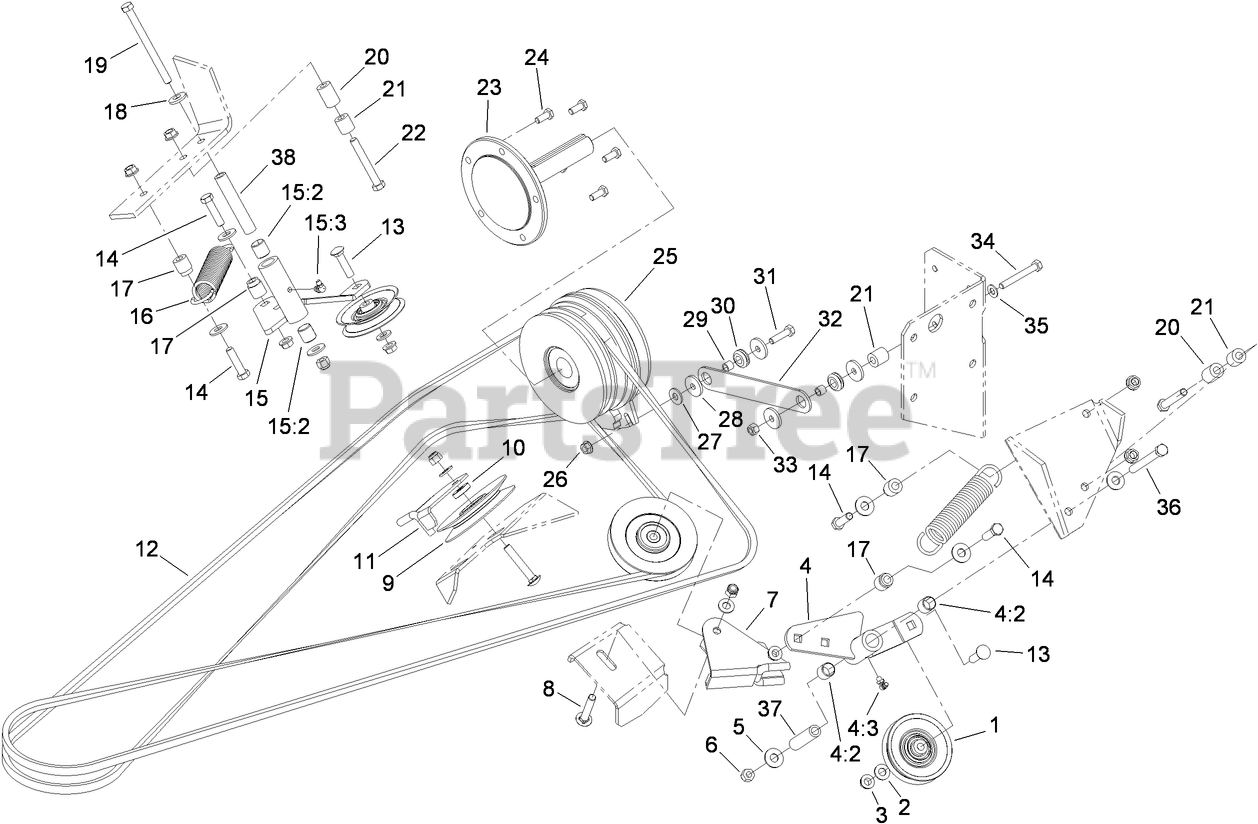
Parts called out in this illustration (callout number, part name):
1	SHEAVE
2	WASHER-FLAT
3	NUT-HHF, WHIZ
4	LH IDLER ASM
4:2	SLEEVE-BEARING
4:3	FITTING-GREASE, 90 DEG
5	WASHER-FLAT
6	NUT-LOCK, NI
7	GUARD-BELT SHEAVE, LH
8	BOLT-CARR, SHORT NECK
9	SHEAVE
10	SPACER-BRACKET, GUIDE
11	GUARD-BELT SHEAVE, RH
12	BELT-V
13	SCREW-HH
14	SCREW-HH
15	RH IDLER ASM
15:2	SLEEVE-BEARING
15:3	FITTING-GREASE, 90 DEG
16	SPRING-EXTENSION
17	SPACER-TIGHTENER, BELT
18	WASHER-BELLEVILLE
19	SCREW-HH
20	SPACER-HYDRO CONTROL, LH
21	SPACER-STRAP, CLUTCH
22	SCREW-HH
23	SHAFT-STUB
24	SCREW-HH
25	CLUTCH KIT
26	NUT-HF
27	WASHER-FLAT
28	WASHER
29	SPACER
30	GROMMET
31	SCREW-HH
32	STRAP-CLUTCH / BRAKE
33	NUT-LOCK, NI
34	SCREW-HH
35	WASHER-PLAIN
36	SCREW-HH
37	BUSHING-TIGHTENER, PIVOT
38	BUSHING-TIGHTENER, PIVOT
